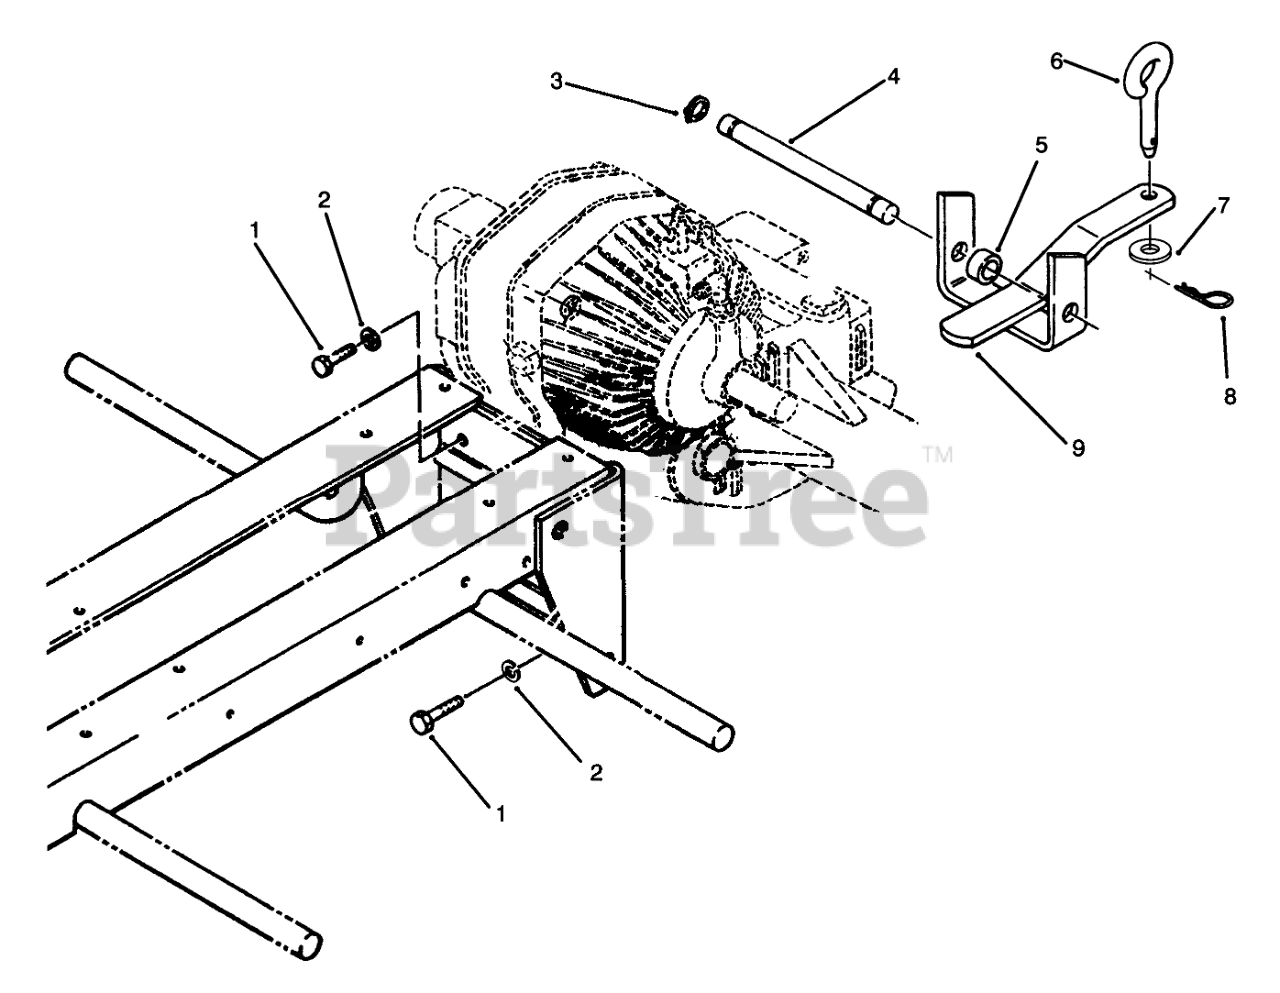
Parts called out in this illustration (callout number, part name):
1	SCREW-HH
2	WASHER-LOCK
3	E-RING
4	PIN-STATIONARY HITCH
5	Spacer
6	PIN-TOOL
7	WASHER-FLAT
8	Hairpin Cotter
9	Hitch
